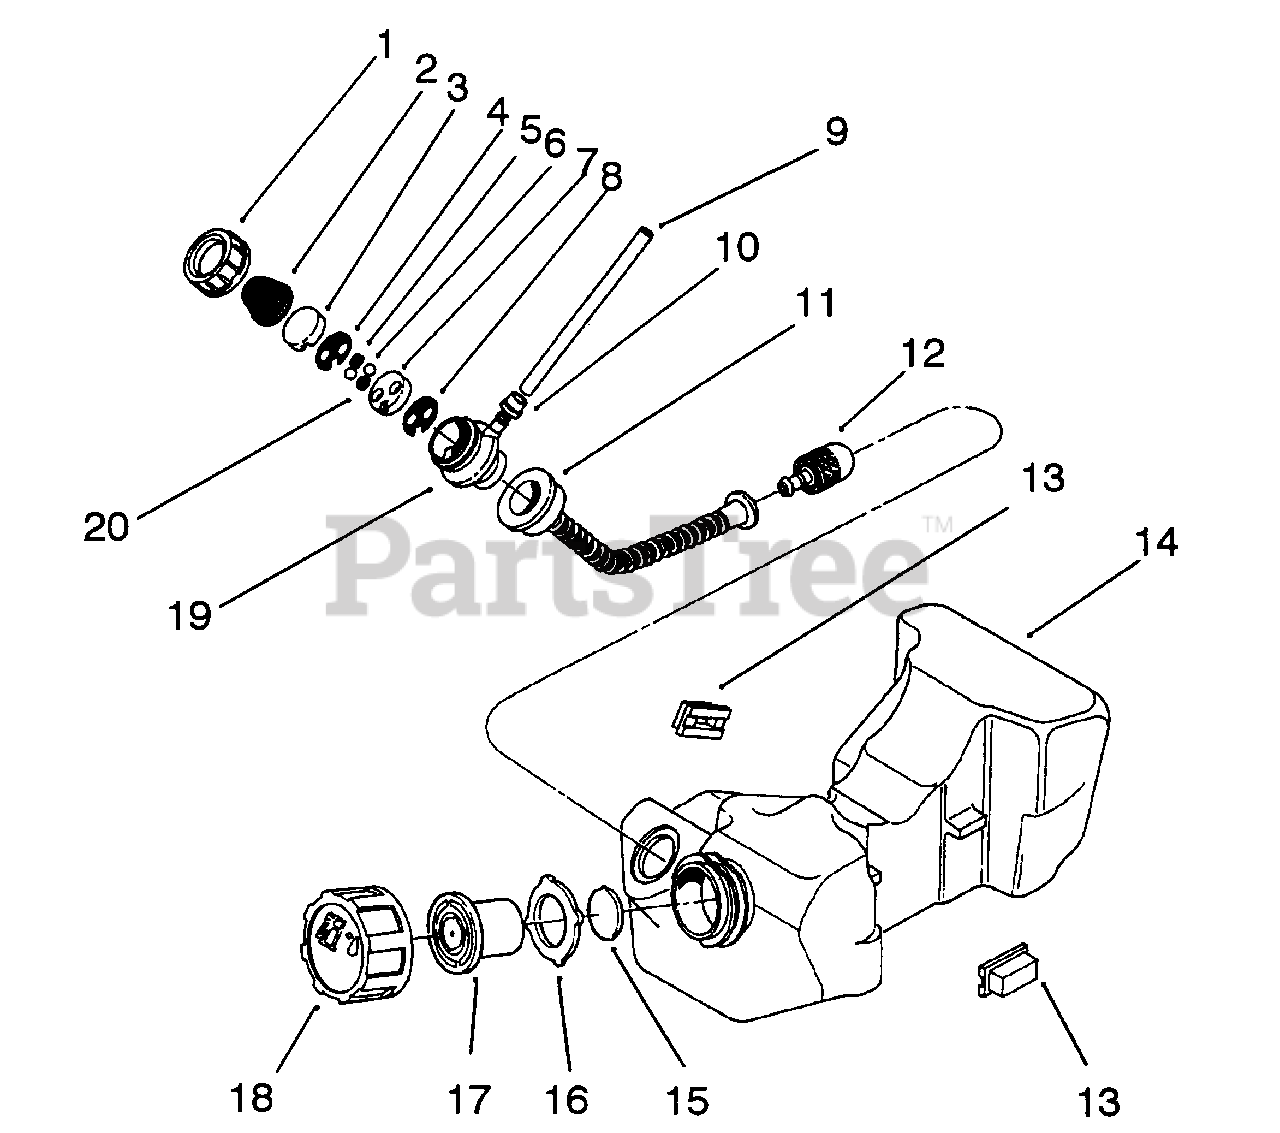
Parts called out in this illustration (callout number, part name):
3	Seat-Valve
7	Seat-Valve
9	Tube-Fuel
11	Hose-Suction
12	Filter-Fuel
14	Fuel Tank Assembly (Incl. Ref. #11, 12 15-18 & 19)
17	Valve-Breather
18	Cap-Fuel Tank
19	Pump Priming Assembly (Incl. Ref. #1-8 & 20)
20	Cushion Ball
